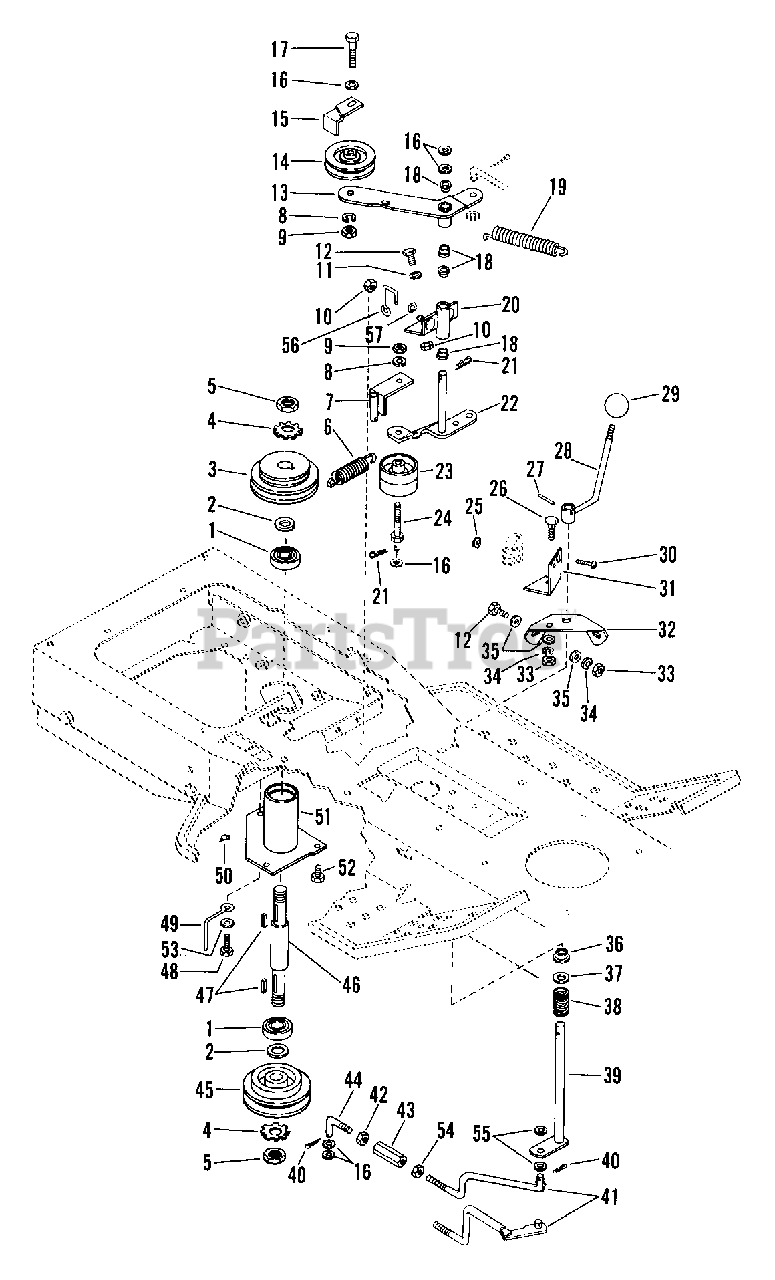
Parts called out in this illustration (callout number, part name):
1	BRG-BALL .750X1.781X.61
2	WSHR-FL-STL .755X1.250X.125
3	SHEAVE-DOUBLE GROOVE
3	DOUBLE GROOVE SHEAVE
4	STAR WASHER
5	NUT-JAM .75-10 PL
6	SG-TENS .112X.89X5.28 WLD 56
7	BRACKET
8	WSHR-LK .375X.115 HVY PL
9	NUT-HEX .375-16
10	NUT-LK .312-18 GR A PL
11	WSHR-FL-STL.312X.734X.065PL
12	BLT-HEX .31-18X.75 PL GR5
13	IDLER ARM
14	IDLER-V 3.06 X .38
15	BELT RETAINER
16	WSHR-FL-STL.406X.812X.065PL
17	BLT-HEX .38-16X1.75 PL GR2
18	BSHG-FLG .372X.500X.312X.625NY
19	SG-TENS .105X.812X3.88 WLD 15
20	IDLER PIVOT
21	PIN-HAIR INT .08X.18X1.18
22	IDLER ARM
23	IDLER-FLAT 2.25 X .38
24	BLT-HEX .38-16X1.75 PL GR2
24	IDLER MTG BOLT
25	NUT-KEPS 10-24 PL
26	BLT-RDHDSQNK .31-18X.75 GR5 PL
27	PIN-ROLL .188X1.25
28	P T O HANDLE
29	SHIFT BALL
30	SCR-MCH 10-24X1.00 SLRH PL
31	SWITCH BRACKET
32	BRACKET
33	NUT-HEX .312-18
34	WSHR-LK .312X.097 PL HVY
35	WSHR-FL-STL .323X.625X.062 PL
36	BSHG-FLG.500X.625X.312X.750NY
37	WSHR-FL-STL .531X1.062X.095 PL
38	SG-COMP .080X.85X1.44
39	PTO LEVER
40	PIN-COTR .12X1.0 PL
41	IDLER LINK
42	NUT-JAM .375-16 PL
42	NUT-HEX .375-16
43	NUT-CUPLG .375-16 PL
43	NUT-CUPLG RH & LH THD .37-16PL
44	IDLER ADJUSTOR LINK
45	SHEAVE-JACKSHAFT
46	JACKSHAFT
47	KEY-SQ .188X1.0X.188 SAE 8630
48	BLT-HEX .31-18X1.00 PL GR 2
49	BELT FINGER
50	HYDRAULIC LUBRICATION FITTING
51	SPINDLE HOUSING
52	BLT-HEX .31-18X1.50 PL GR2
53	WSHR-FL-STL .328X1.0X.094 PL
54	NUT LH THD .375-16 GR 2 PL
55	WSHR-FL-STL .382X.812X.023 PL
56	BELT FINGER
57	WSHR-LK-EXT .313X.030 PL
